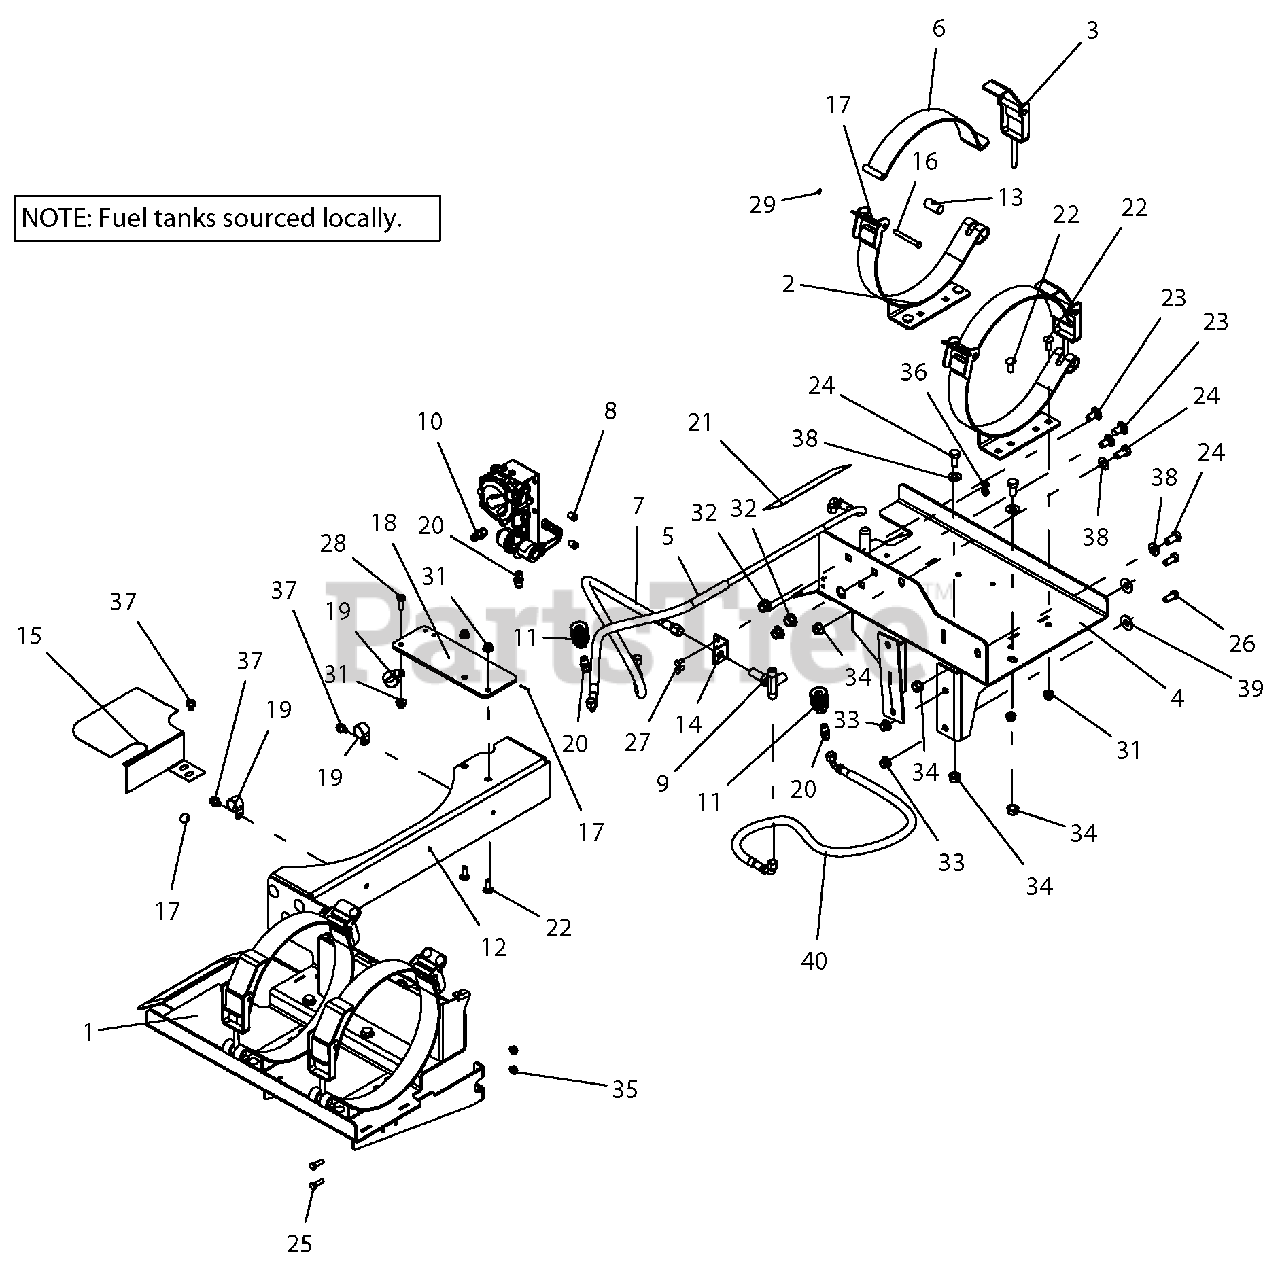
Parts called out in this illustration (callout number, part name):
1	WLDMT, TANK -LH LP
2	WLDMT, CLAMP LP TANK
3	ASM, LP TANK HANDLE CLAMP
4	WLDMT, LP TANK MOUNTING - LH-BLACK
5	HOSE, LPG SS25UL-6-4-6-45"
6	WLDMT, UPPER LP TANK CLAMP
7	HOSE, LPG SS25UL 6-4-6-30.00
8	PLUG, PIPE 1/4 NPT
9	VALVE, SHERWOOD T PV3866 LPG
10	FTG, BARB 1/2HOSE-3/8MNPT
11	FTG, LPG TANK COUPLER -LH THRD
12	CROSS MEMBER, TANK MOUNTS - LP
13	PIVOT, LP CLAMP HANDLE
14	BRKT, TEE VALVE- MOUNTING
15	GUARD, LP-MUFFLER-BLACK
16	PIN, LP CLAMP
17	MAGNET, .75X.060, LP CLAMP
18	PLATE, REGULATOR MOUNT, EG
19	CLAMP, CUSHIONED STEEL REV
20	FTG, ADPTR 1/4MNPT X 5/8MJIC
21	DECAL, HORZ. MOWER TANKS ONLY
22	BLT-RDHDSQNK .38-16X1.00 G5 YWZC
23	BLT-RDHDSQNK .50-13X1.00 G5 Y
24	BLT-HEX .50-13X1.00 GR5 YWZC
25	BLT-HEX .31-18X1.00 GR5 YWZC
26	BLT-HEX .44-14X1.00 GR5 YWZC
27	BLT-HEX .25-20X.63 GR5 YWZC
28	BLT-HEX .38-16X1.00 GR5 YWZC
29	RG-RTNG-EXT .312X.025
31	NUT-LK-NYL-FLG .38-16 YWZC
32	NUT-LK-NYL-FLG .50-13 YWZC
33	NUT-LK-NYL-FLG .44-14 YWZC
34	NUT, LK-TOP-FLG .50-13 YWZC
35	NUT, LK-TOP-FLG .312-18 YWZC
36	NUT, LK-TOP-FLG .25-20 YWZC
37	SCR-TAP .38-16X.50 HWH TR YWZ
38	WSHR-FL-STL.531X1.06X.095YWZC
39	WSHR-FL-STL..50X1.25X.083 YWZ
40	HOSE, LPG SS25UL 6-4-6-45"
